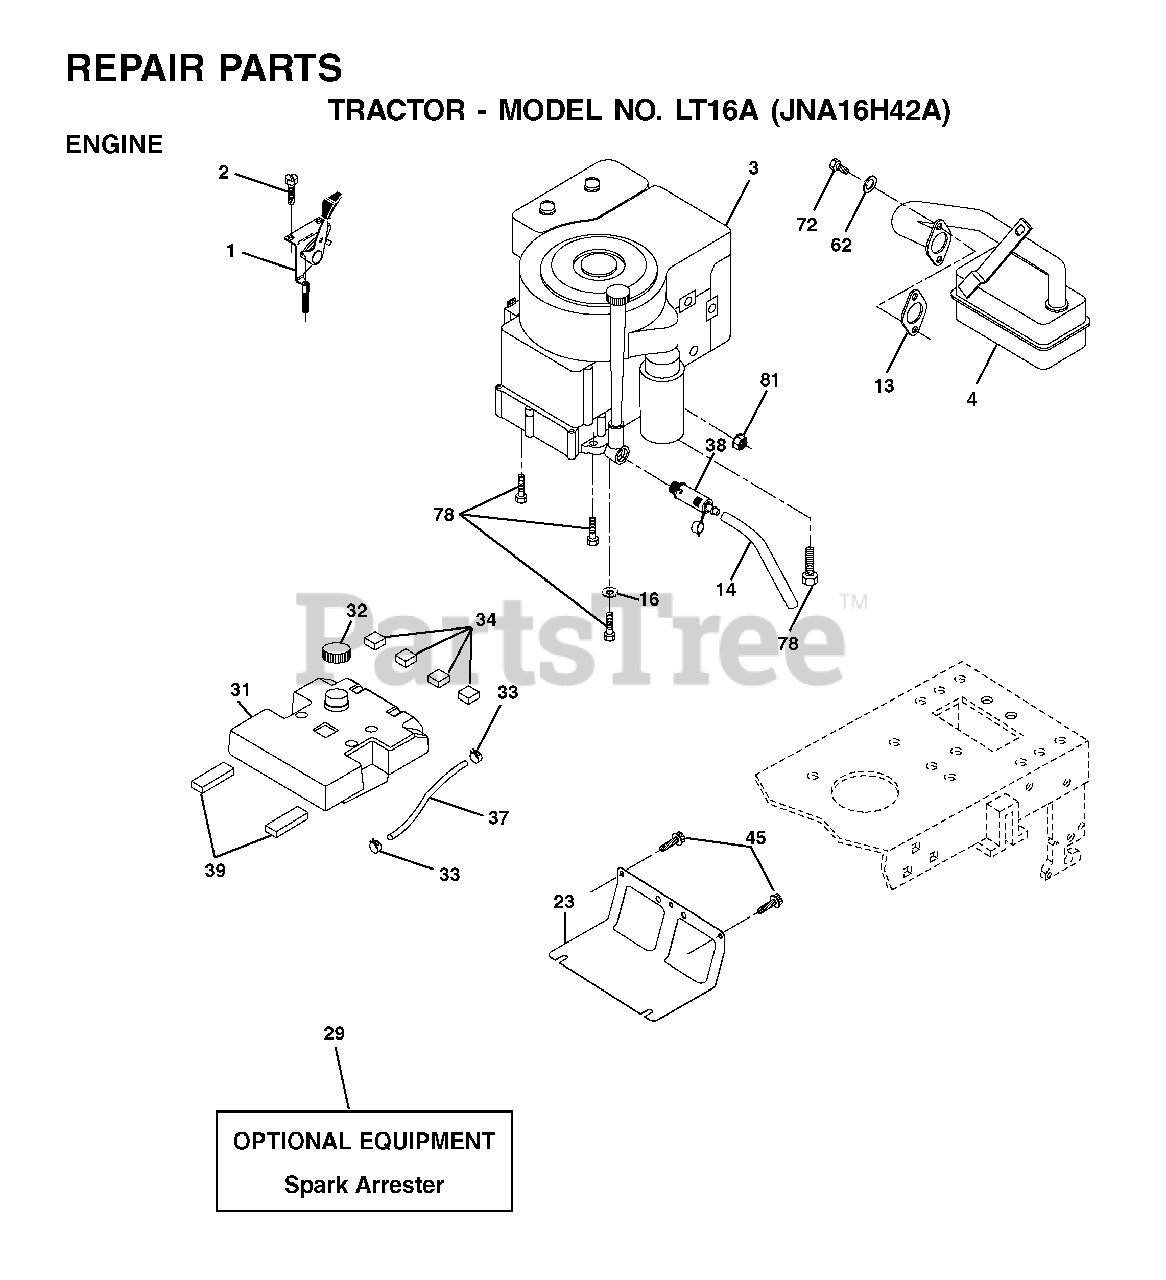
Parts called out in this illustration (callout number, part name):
1	CONTROL TH/CH FLAG
2	SCREW LT
13	REPL BY 532 27 22-93
14	TUBE, DRAIN OIL ASM.
16	LOCKWASHER
23	SHEILD.BROWNING.DBR.GUARD
29	ARRESTER SPARK (OPTIONAL)
31	TANK.FUEL(3.5.GAL)
32	FUEL CAP
33	HOSE CLAMP
34	PAD-SPACER LT
38	PLUG, OIL DRAIN EASY
39	PAD IDLER TI
45	SCREW, 3/8-16X3/4
62	LOCKWASHER
72	SCREW
78	SCREW.3/8-16
81	NUT
